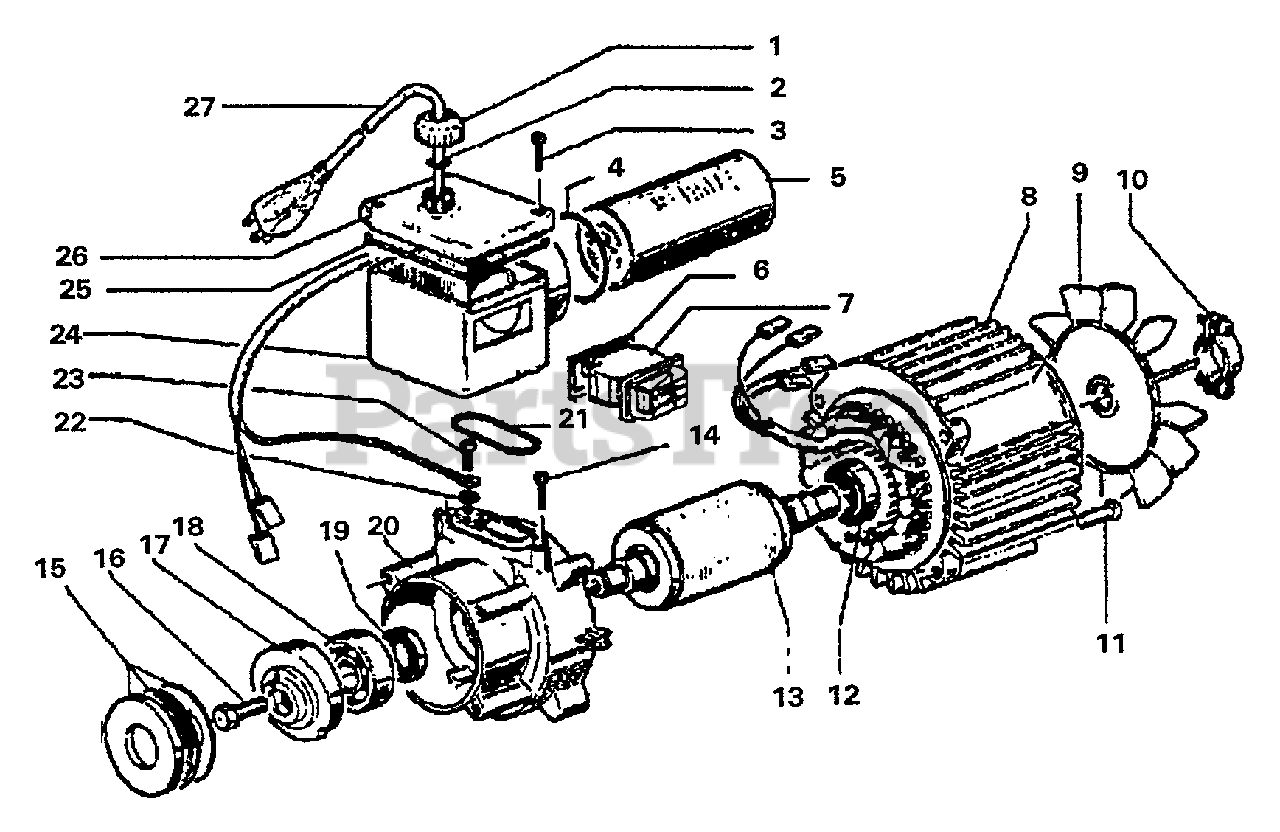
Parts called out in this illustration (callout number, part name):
1	NUT, WING
2	O-RING 0.296×.084
3	SCREW M4×18
4	O-RING 1.925×.103
5	CONDENSER
6	GASKET, SWITCH
7	SWITCH, IGNITION
8	STATOR
9	FAN
10	RING, LOCK
11	SCREW - 6×30
12	BEARING, BALL
13	ROTOR
14	SCREW - 4×13
15	AXLE, BEARING
16	SCREW
17	PLATE, CAM
18	BEARING, BALL
19	SEAL, OIL
20	CRANKCASE
21	O-RING 1.549×.103
22	WASHER M5.3
23	SCREW
24	COVER
25	O-RING 3.237×.103
26	COVER
27	CABLE, COMPLETE
